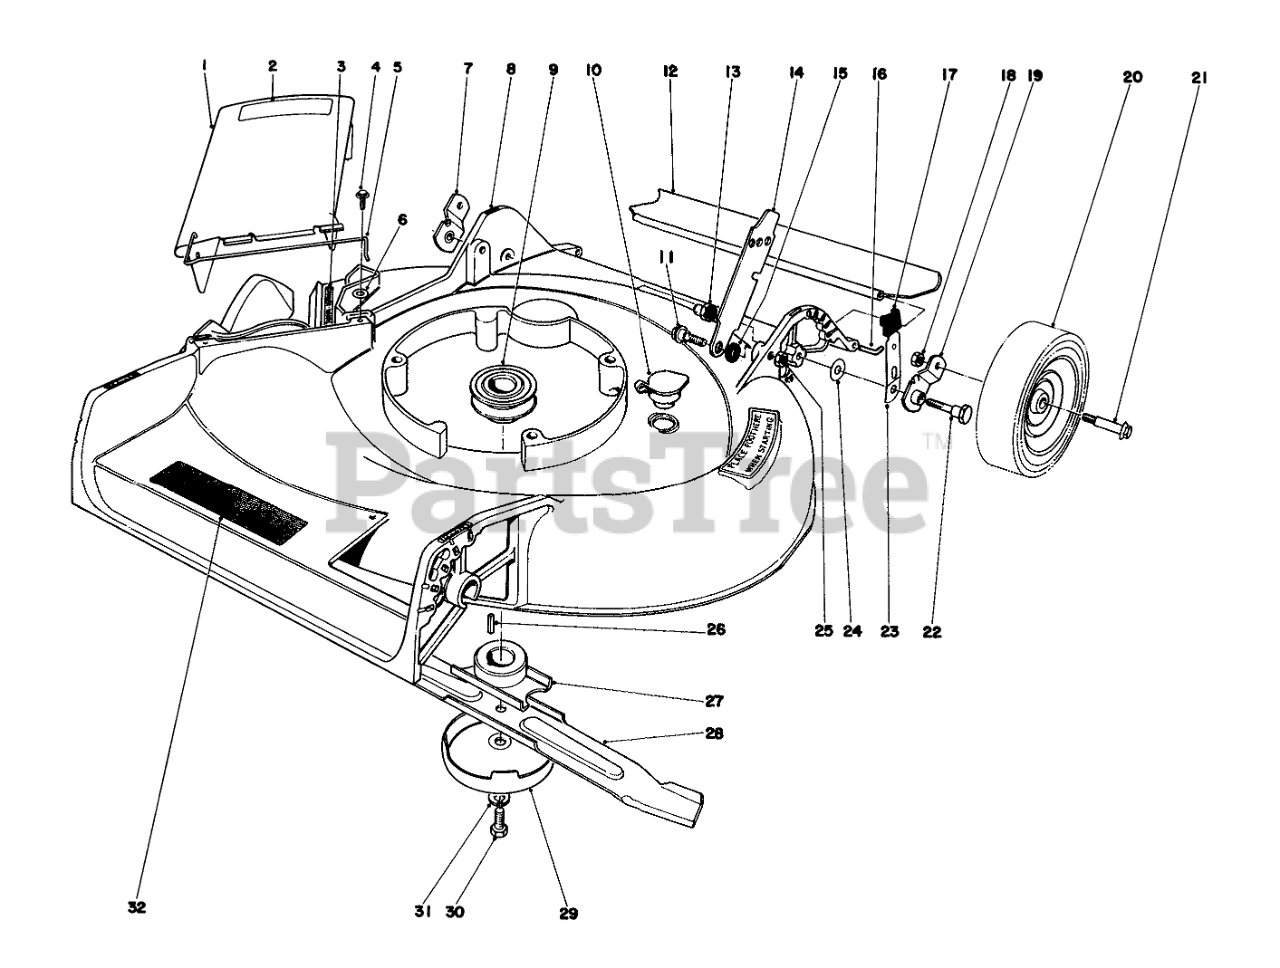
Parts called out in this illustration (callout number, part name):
1	Deflector Cover Assembly (Incl. Ref. #2 & 5)
2	Caution Decal
3	Decal
4	SCREW
5	SPRING HINGE
6	WASHER-FLAT
7	Pivot Arm
8	Housing
9	DRIVER PULLEY
10	WASHOUT PLUG
11	SCREW-SHOULDER
12	REAR SAFETY SHIELD 21
13	HANDLE PIVOT NUT
14	Latch
15	HANDLE LATCH SPACER
16	SHIELD ROD
17	KNOB-ARM
18	Nut
19	Pivot Arm
20	Wheel Assembly
22	5/16-18 PIVOT SCREW
23	SPRING ARM ASM
24	WASHER-PIVOT
25	Nut
26	KEY-SQUARE
27	Blade Retailer
28	Blade
29	AntiScalp Cup
30	SPECIAL SCREW
31	WASHER-LOCK
32	Decal-Deck
